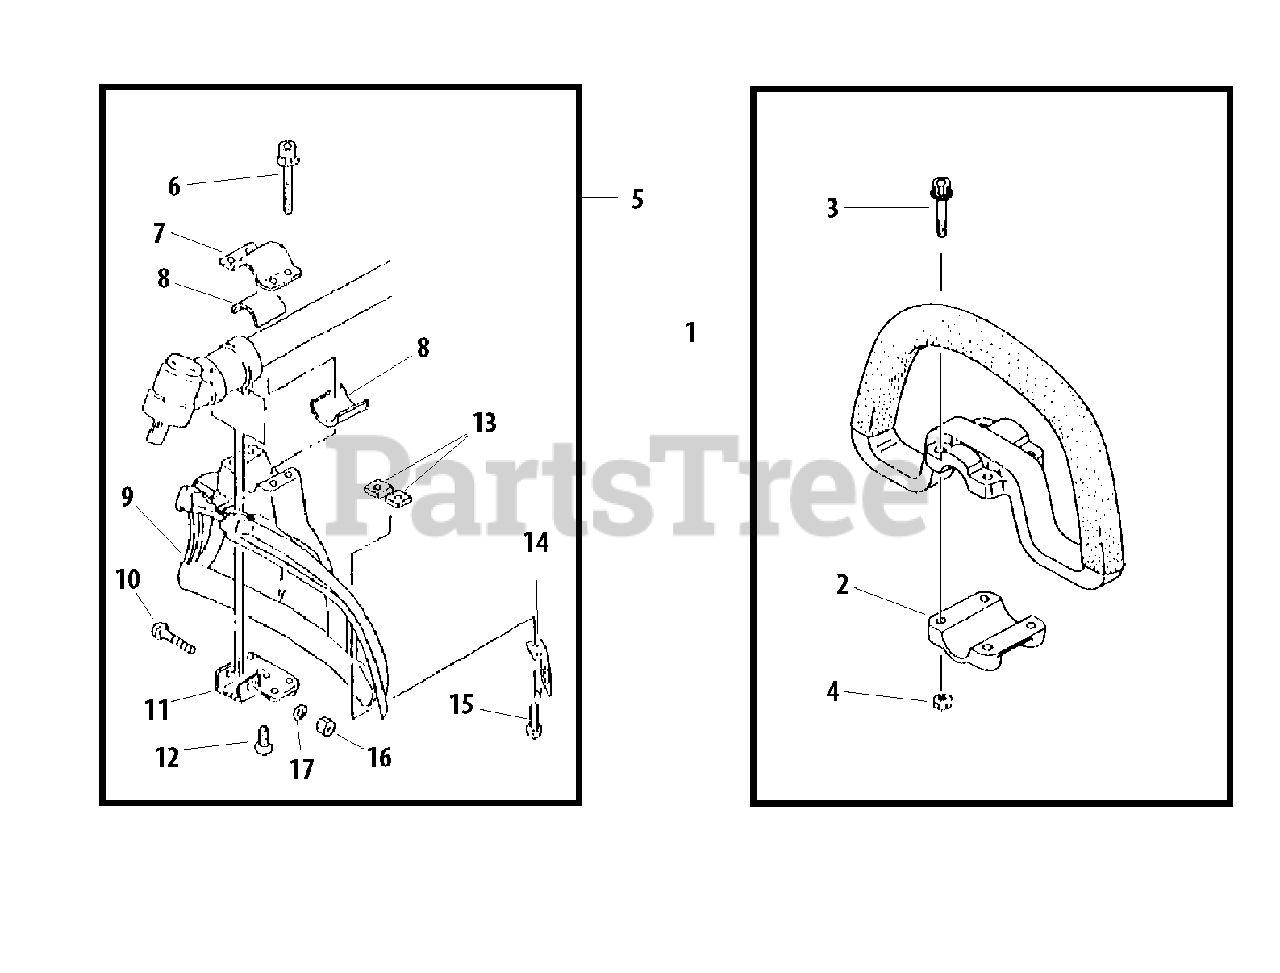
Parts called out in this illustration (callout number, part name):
1	HANDLE ASSY
2	CAP - LOWER
3	SCREW - 5X30
4	NUT - 5
5	DEBRIS SHIELD KIT - BLACK
6	SCREW - 5X45
7	CLAMP - UPPER
8	SPACER
9	SHIELD, DEBRIS - BLACK
10	SCREW - 5X35
11	CLAMP - LOWER
12	SCREW
13	NUT - 5
14	KNIFE, TRIMMER LINE
15	SCREW - 5X16
16	NUT - 5
17	WASHER - 5
